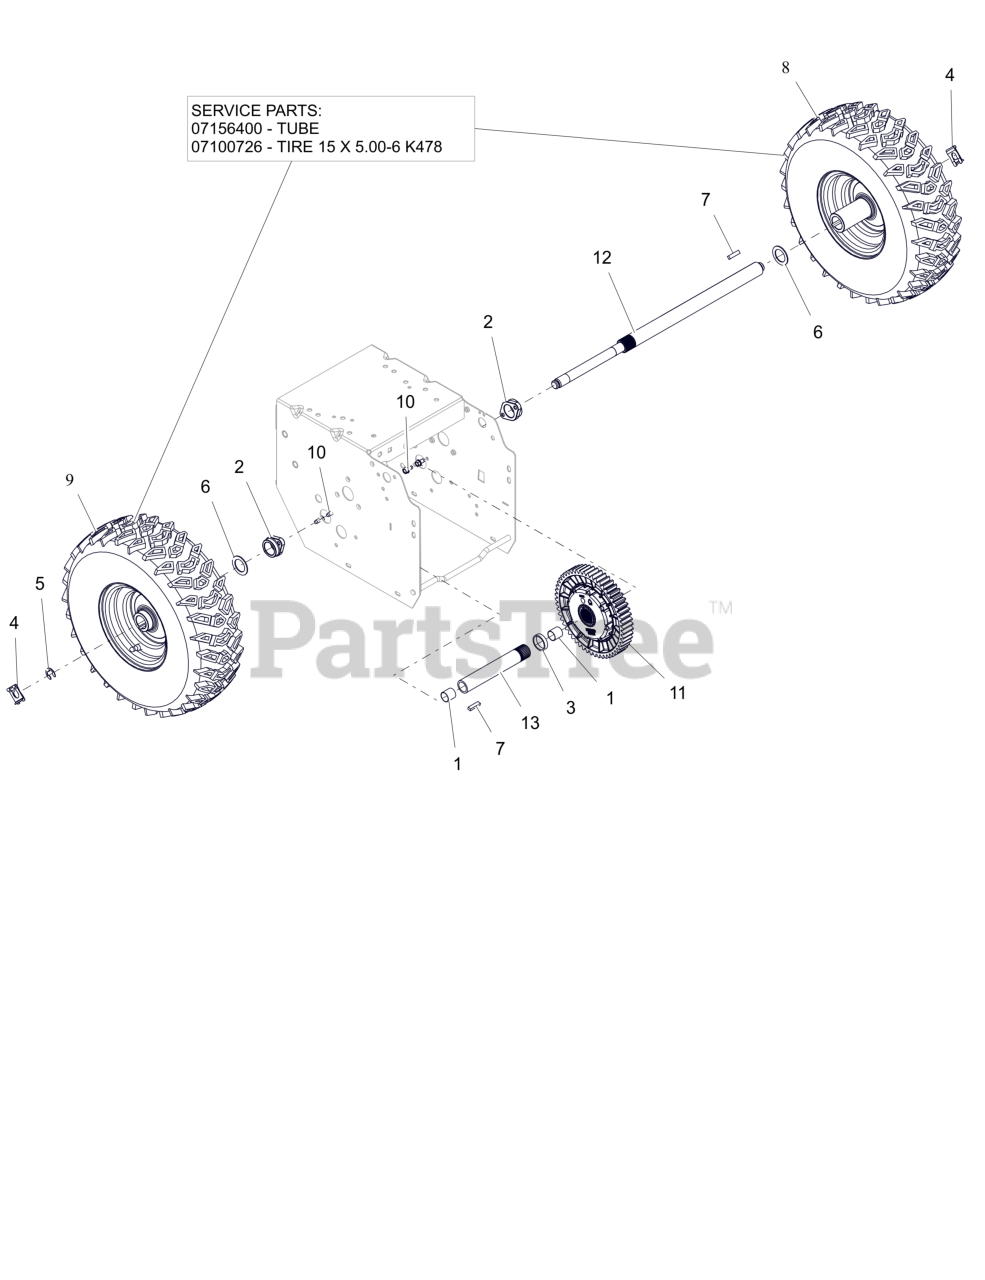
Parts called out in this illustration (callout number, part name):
1	BSHG-SLV .706X.764X.75 BRZ
2	BSHG, AXLE 1.000X1.380X.650
3	BSHG, SLV 1.062X1.228X.268
4	CLIP, SNAP .625 DIA
5	RG-RTNG-EXT .625X.042
6	WSHR, FLT 1.010X1.505X.062 ZCC
7	KEY-RECT .25X.188X1.00
8	TIRE/WHEEL LH 15X5.00-6 REMOTE
8	TUBE 15 X 5.00-6
8	TIRE, 15X5.00-6 K478
9	TIRE/WHEEL RH 15X5.00-6 REMOTE
9	TUBE 15 X 5.00-6
9	TIRE, 15X5.00-6 K478
10	SCR-TAP .25-20X.50 HWH ZCC
11	DIFFERENTIAL, AUTOMATIC
12	AXLE, LONG - COMPACT AUTO DIFF
13	AXLE, SHORT - W/BUSHINGS
